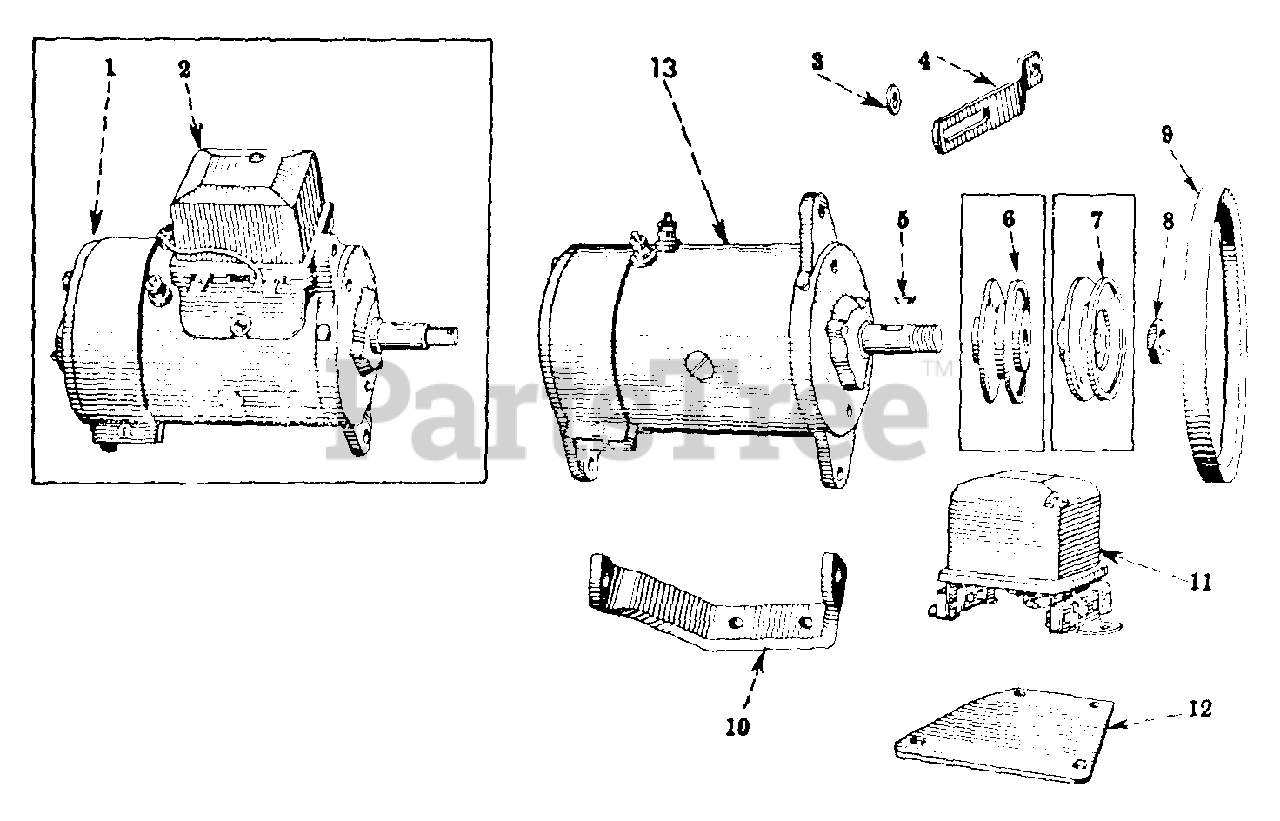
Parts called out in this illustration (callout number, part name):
1	GENERATOR ASSY - 6 VOLT
2	RELAY ASSY.
3	WASHER, 11/32 X 3/4 X .105
4	BRACE, GENERATOR
5	KEY, 1/8 X 5/8 WOODRUFF NO. 5 ALY-STL
6	PULLEY, GENERATOR
7	PULLEY, GENERATOR
8	NUT, ARMATURE SHAFT
9	BELT, GENERATOR
10	BRACKET, GENERATOR
11	REGULATOR ASSY VOLTAGE - 6 VOLT
12	BRACKET, VOLTAGE REGULATOR MOUNTING
13	GENERATOR ASSY - 6 VOLT
